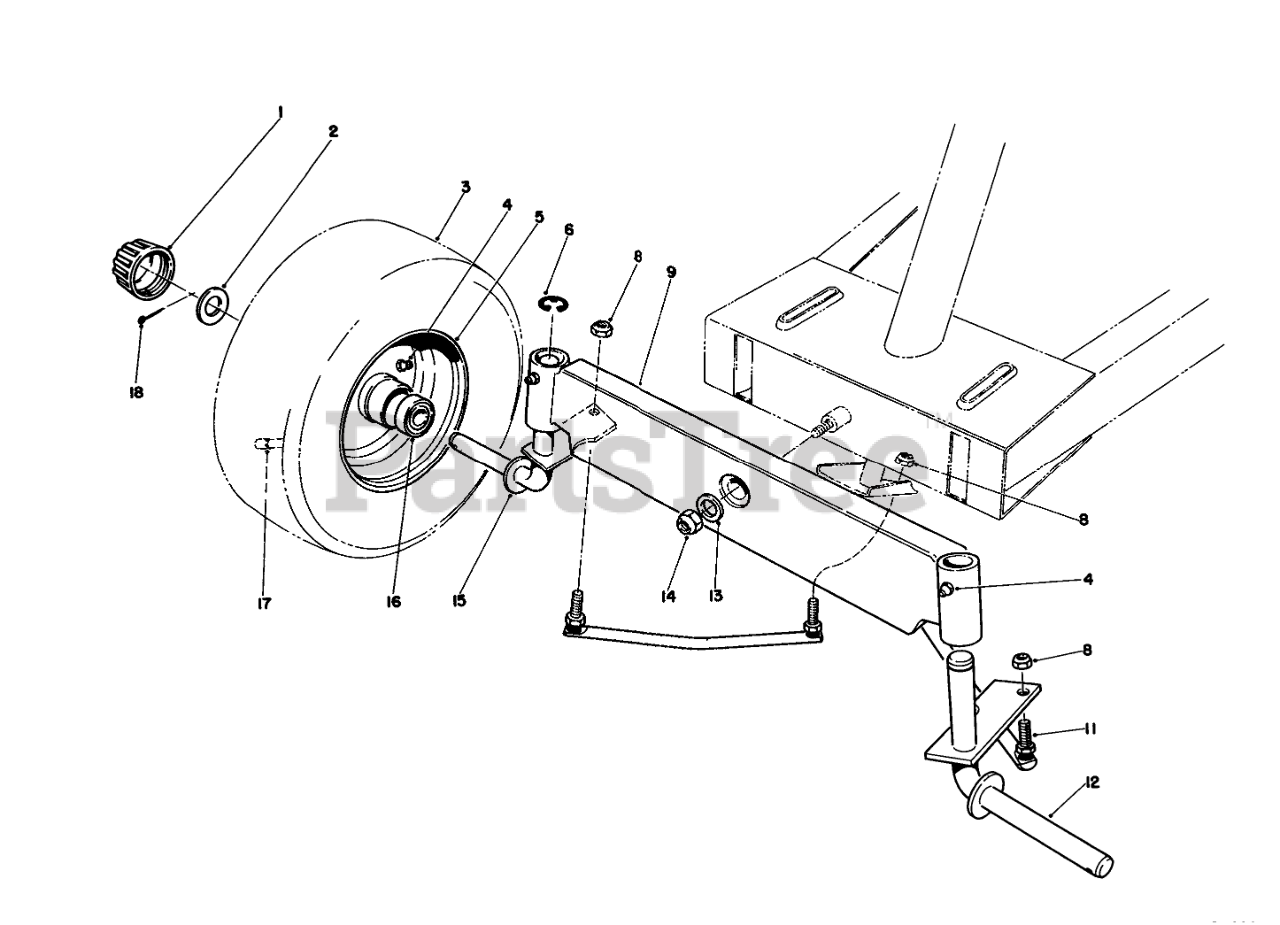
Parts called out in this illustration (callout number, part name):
1	CAP-HUB
2	WASHER-PLAIN
3	TIRE,PNEU.11X4.00X5
4	FITTING-GREASE
6	E-RING
8	NUT-LOCK
9	Axle-Front
11	TIE ROD ASM
12	Spindle-L.H.
13	WASHER-FLAT
14	NUT-LOCK, NI
15	Spindle-R.H.
16	Bearing
17	STEM-VALVE
18	PIN-COTTER
